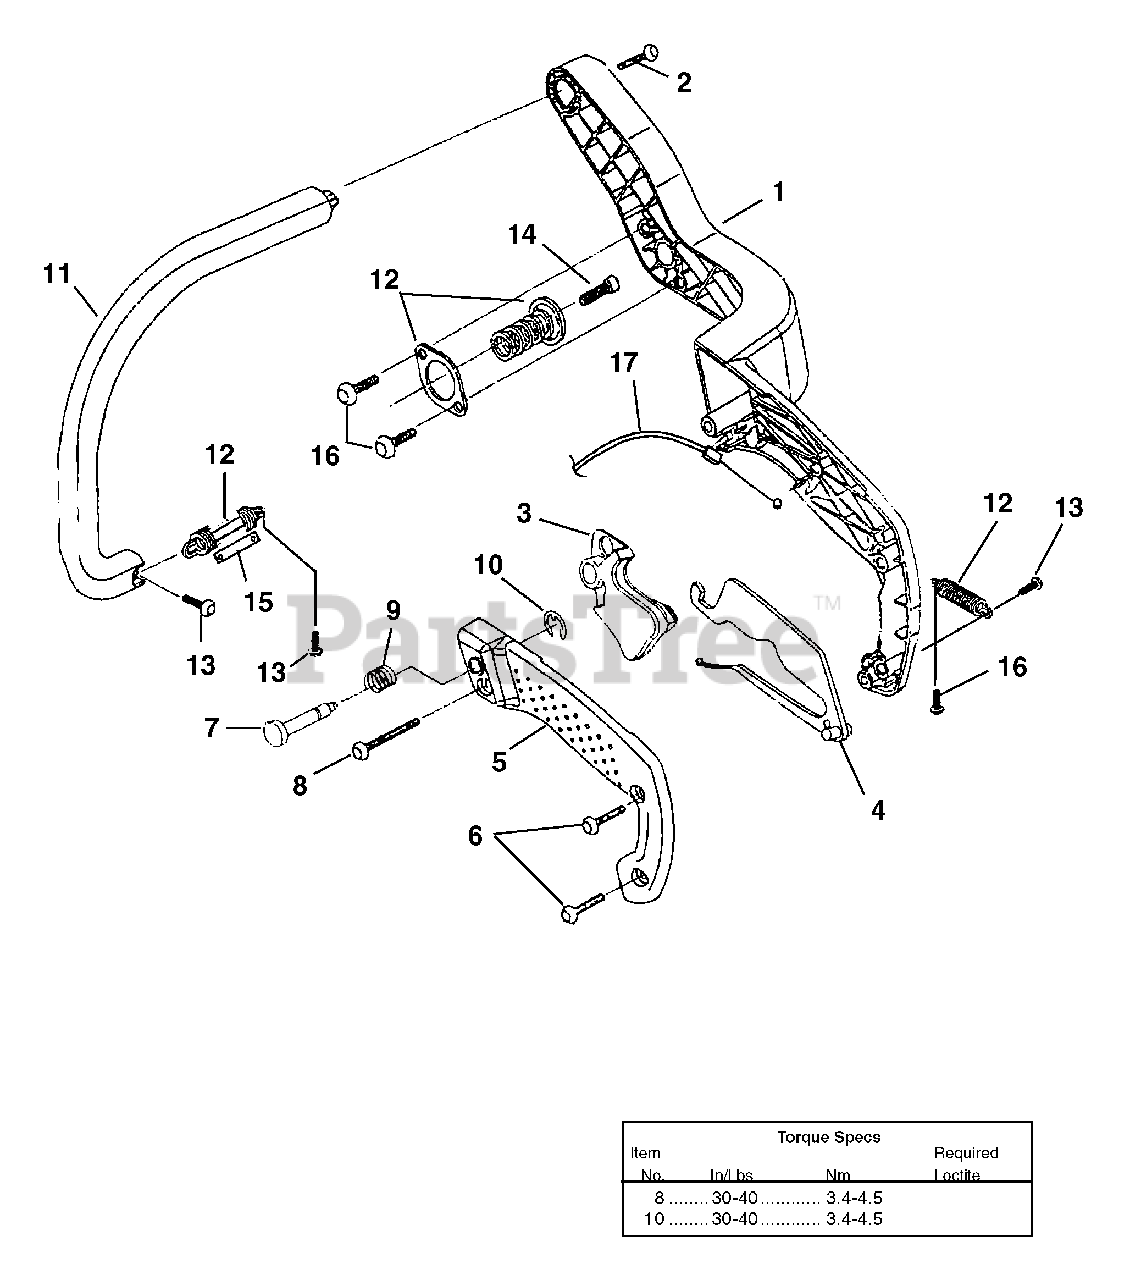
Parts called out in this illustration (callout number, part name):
1	Rear Handle Kit
2	Screw-Pan Hd. (12-14 x 1 1/2")
2	Screw-Pan Hd. (12-14 x 1 1/2")1
3	Trigger, Throttle
4	Throttle Lock Out
5	Handle Cover Kit
6	Screw, Thread Form (10-14 x 3/4")
7	Throttle Lock Pin
8	Screw, Thread Form (10-14 x 11
9	Spring
11	Front Handle Kit
12	Isolator Kit
13	Screw, Truss Hd. (10-14 x 5/8")
14	Screw, Truss Hd. (10-24 x 5/8")
15	Limiter, Isolator
16	Screw, Thread Form (10-14 x 1/2")
17	Throttle Cable
